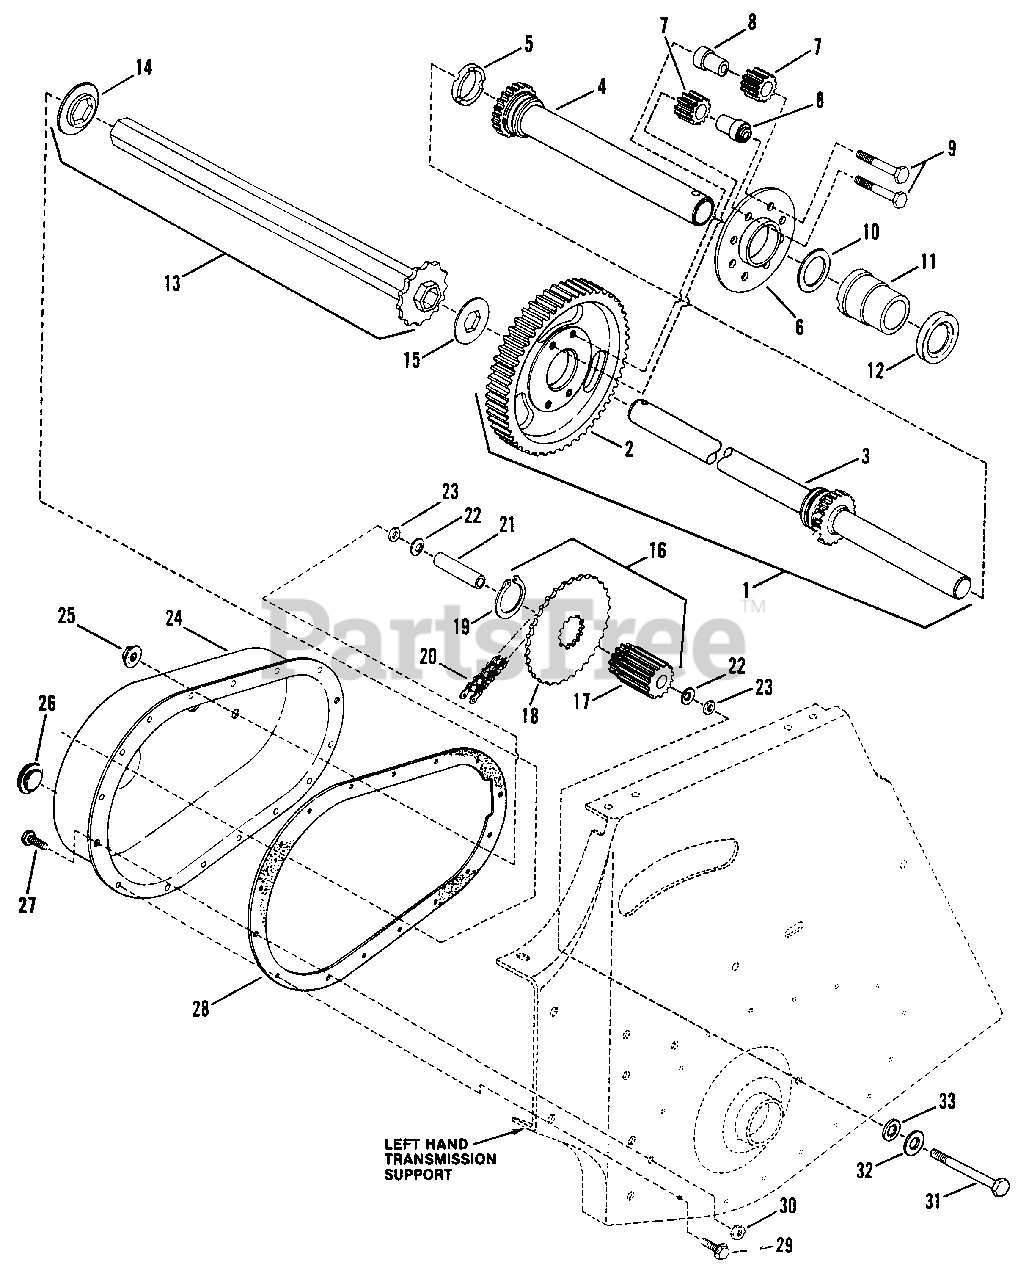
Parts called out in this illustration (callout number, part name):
1	ASSEMBLY, Differential
2	GEAR, 63 Teeth, 10 Pitch
3	AXLE, Long
4	AXLE, Short
5	SPACER, Differential (1.25" ID x .425 Wide)
6	PLATE, Differential
7	PINION GEARS, Differential
8	SPACER, Pinion
9	BOLT, 5/16-24x1-5/8" Hex, Special Lock Cap
10	WASHER, Thrust
11	BEARING, Axle, LH. Transmission Support
12	SEAL, OIL
13	ASSEMBLY, Drive Hex Tube
14	WASHER,Hex Insert
15	WASHER, Thrust
16	ASSEMBLY, Gear &. Sprocket
17	GEAR, 11 Teeth, 10 Pitch
18	SPROCKET
19	RING, Retaining
20	CHAIN, 46 Pitch (#35)
21	SPACER
22	WASHER, Belleville
23	O-RING, 5/16"
24	CASE, Transmission
25	NUT, 5/16-24 Hex Flange Lock
26	PLUG, Oil Fill & Check
27	SCREW, 1/4-20 x 5/8" Hex Head Cap
28	GASKET, Transmission Case
29	SCREW, 1/4-20 x 5/8" Self-Tapping
30	NUT, 1/4-20 Hex Lock
31	BOLT, Idler, 5/16-24 x 2-5/8"
32	WASHER, Flat
33	WASHER, 5/16" Internal Tooth Lock
